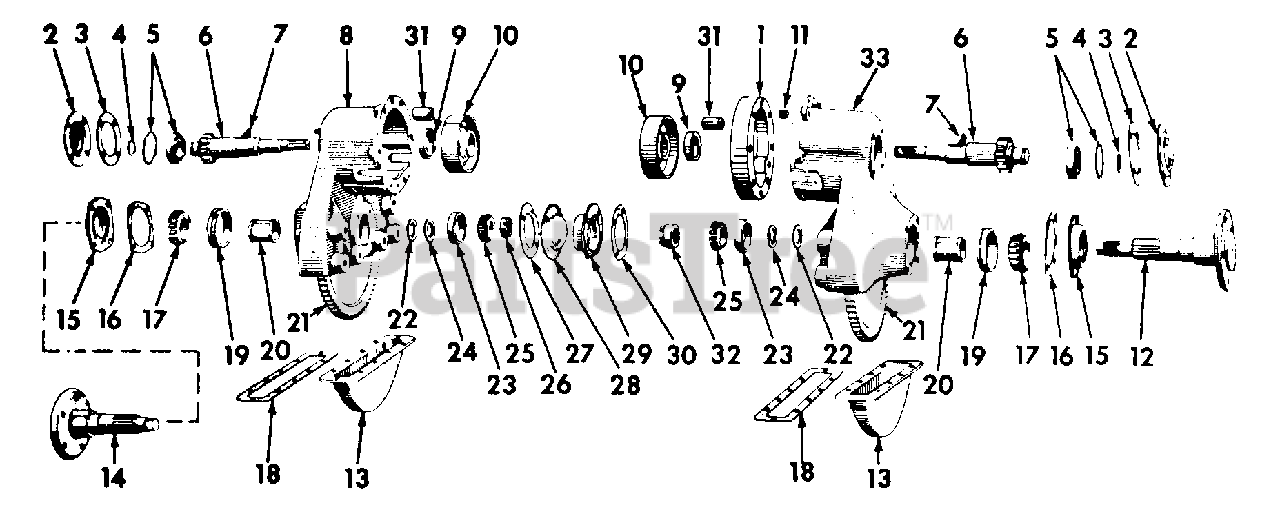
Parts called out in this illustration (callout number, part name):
1	SPACER W/BUSHING, IH-358756-R1, REAR AXLE
2	RETAINER, SHAFT BRG
3	GASKET, BEARING LOCK
4	RING, SHAFT BRG LOCK
5	BEARING ASSY, BALL
6	SHAFT, DIFFERENTIAL
7	KEY, 3/16 X 1 WOODRUFF 13
8	HOUSING ASSY, REAR AXLE LH
9	SEAL, DIFFERENTIAL SHAFT PINION OIL
10	DRUM, BRAKE
11	BUSHING, ACTUATING TOGGLE
12	AXLE, REAR RH
13	PAN, REAR AXLE HOUSING
14	AXLE, REAR LH
15	SEAL, REAR AXLE OIL
16	GASKET, REAR AXLE OIL SEAL
17	BEARING ASSY, OUTER CONE
18	GASKET, REAR AXLE HOUSING PAN
19	BEARING, OUTER CUP
20	SPACER, REAR AXLE BEARING
21	GEAR, REAR AXLE DRIVE 70T
22	SPACER, REAR AXLE DRIVE GEAR
23	BEARING, INNER CUP
24	SHIM, REAR AXLE DRIVE GEAR - .004
24	SHIM, REAR AXLE DRIVE GEAR - .008
24	SHIM, REAR AXLE DRIVE GEAR - .015
24	SHIM, REAR AXLE DRIVE GEAR - .030
25	BEARING ASSY, INNER CONE
26	NUT, REAR AXLE LH
27	GASKET, REAR AXLE BRG CAP LH
28	CAP, REAR AXLE BRG LH
29	CAP, REAR AXLE BRG RH
30	GASKET, REAR AXLE BRG CAP RH
31	BUSHING, ACTUATING TOGGLE
32	NUT, REAR AXLE RH
33	HOUSING ASSY, REAR AXLE RH
